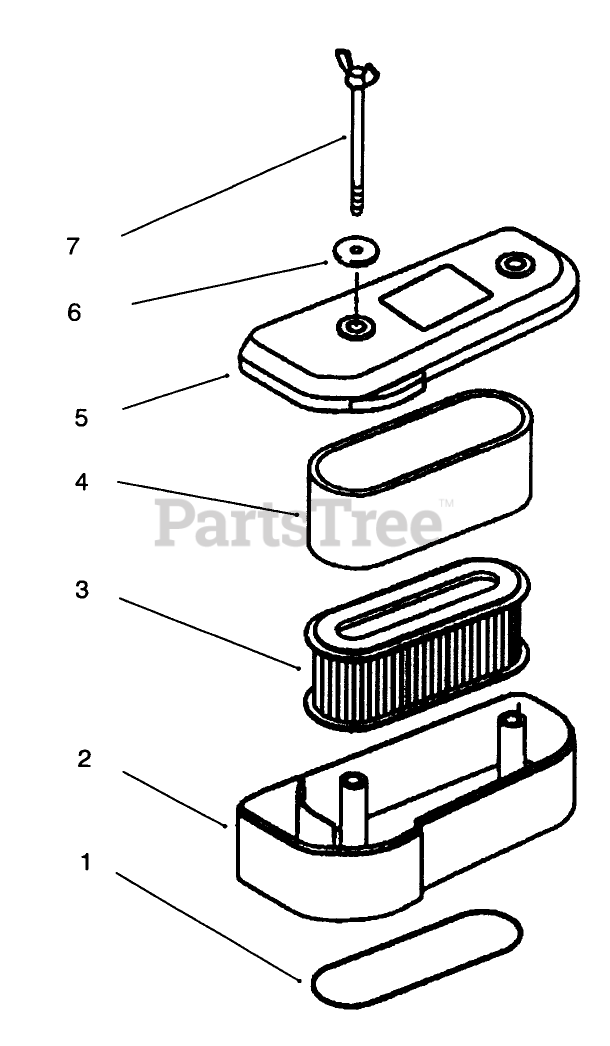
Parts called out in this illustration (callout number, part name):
1	Gasket
2	CASE-Air Filter
3	Element
4	Element
5	CAP-Air Filter
6	Washer
7	Bolt
